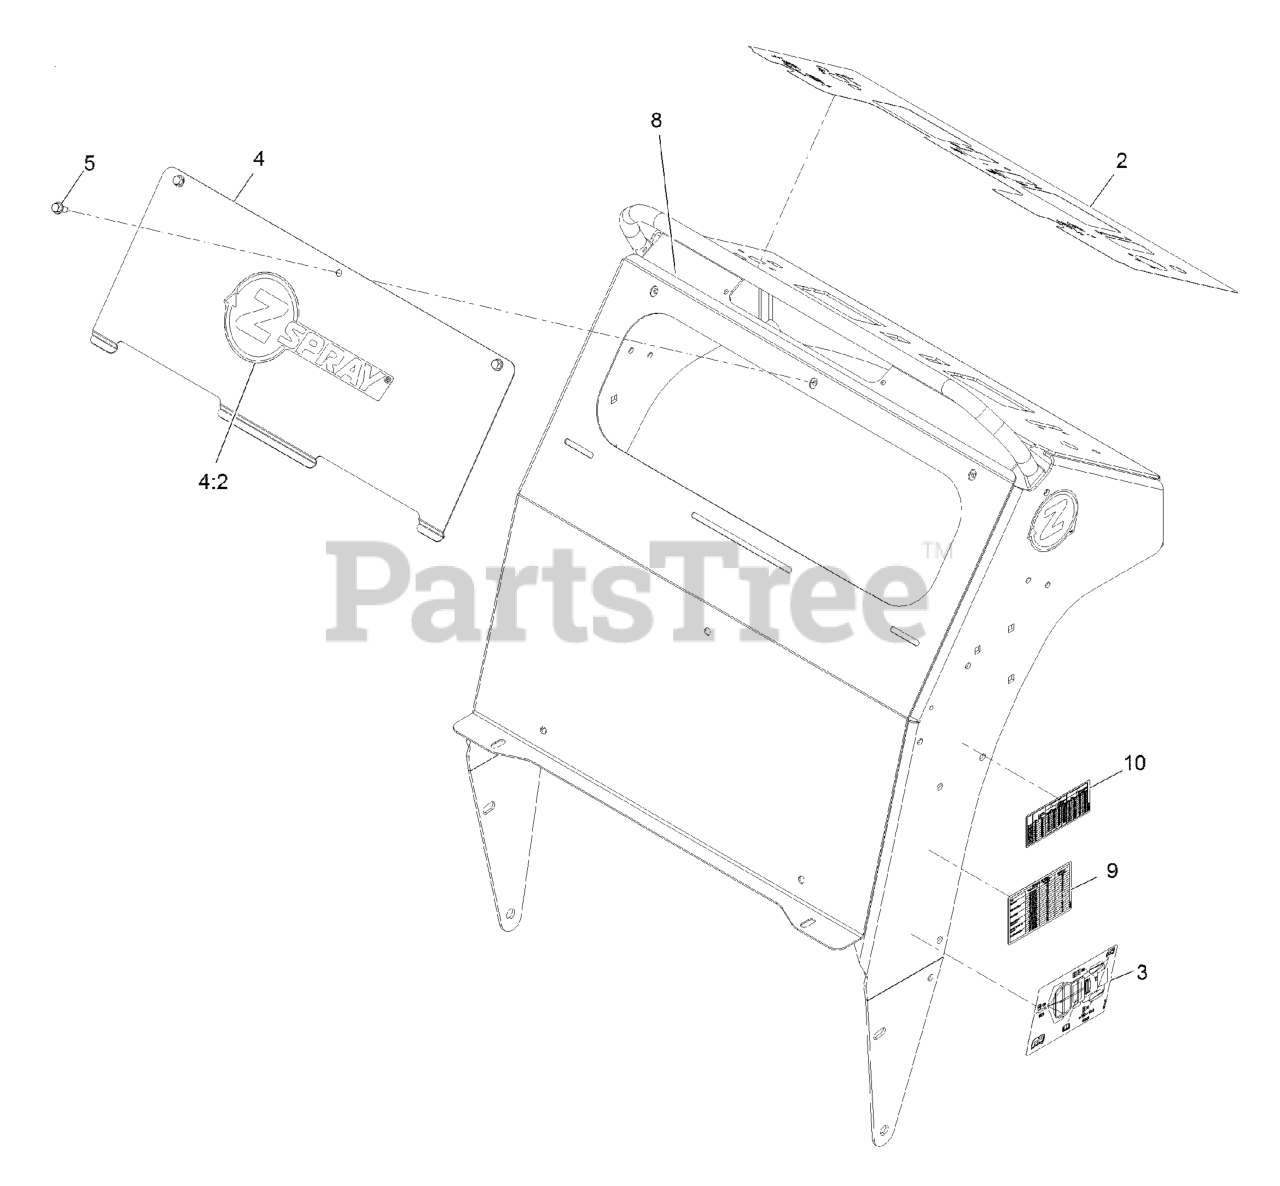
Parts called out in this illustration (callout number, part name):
2	Decal-Control
3	DECAL-SERVICE AID
4	ACCESS PANEL W/ DECAL
4:2	Decal-Z-Spray
5	SCREW-HWH
8	Decal-Z-Logo
9	Decal-Spread Chart
10	Decal-Spray Chart
